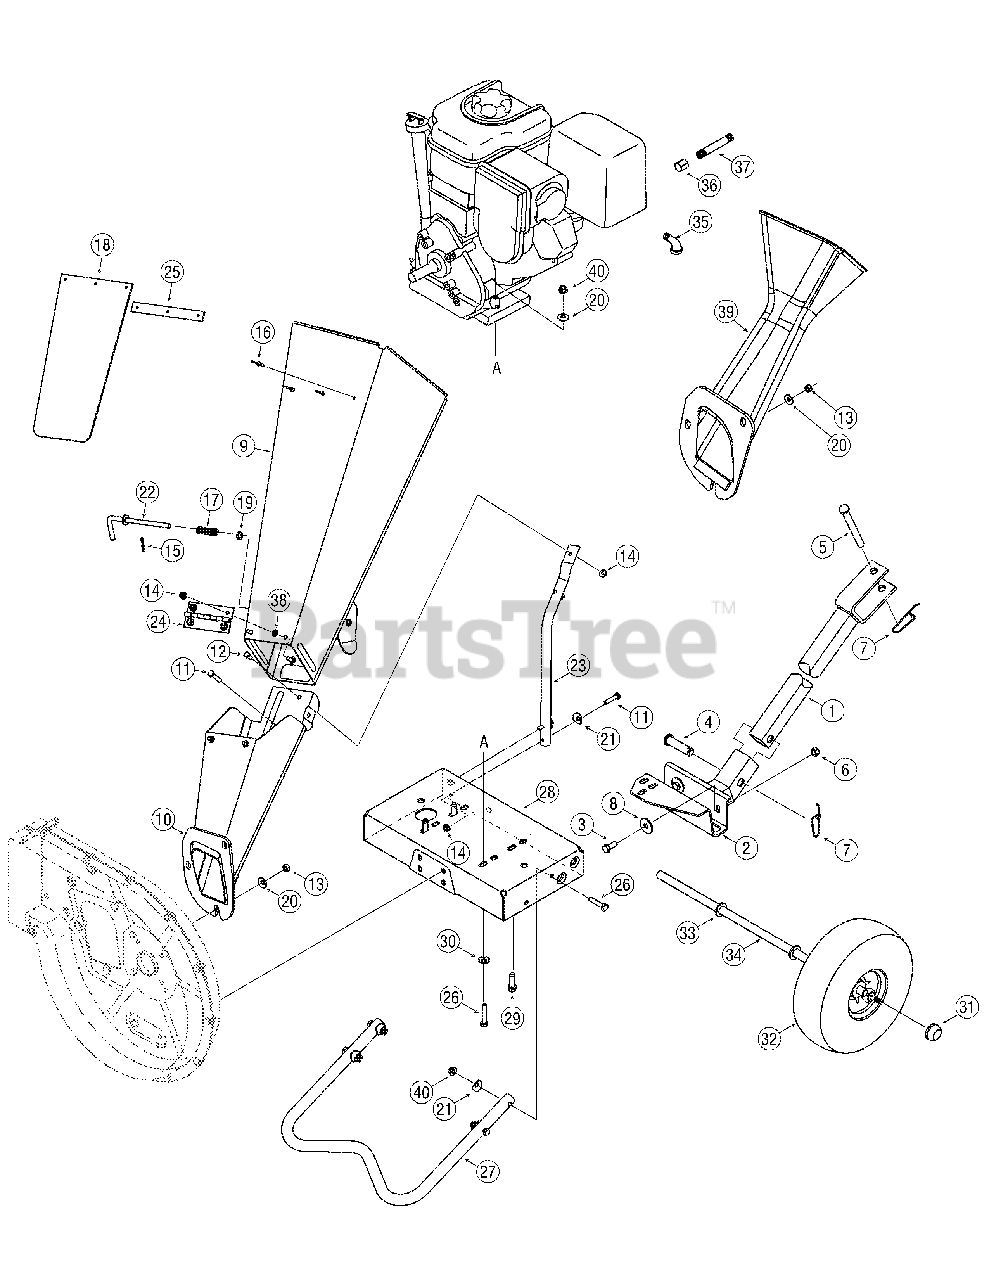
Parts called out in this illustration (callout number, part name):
3	Hex Cap Screw, 3/8-16 x.88
4	Clevis Pin,.625 x 2.4
5	Clevis Pin,.50 x 4.62
6	Flange Lock Nut, 3/8-16
7	Spring Pin
8	Flat Washer,.411 x 1.25 x 1.0
11	Hex Cap Screw, 1/4-20 x 1.25
12	Screw, 1/4-20 x .50
13	Hex Nut, 5/16-18
14	Flange Lock Nut 1/4-20
15	Cotter Pin
16	Pop Rivet
17	Compression Spring,.531 x 1.75
18	Chute Flap
19	Flat Washer
20	Bell Washer.340 ID x.872 OD
21	Washer,.320 ID x.93 OD
22	Lock Rod
24	Chipper Chute Hinge
25	Chute Flap Strip
26	Hex Cap Screw, 5/16-18 x 1.50
29	Hex Sems Screw, 3/8-16 x 1.25
30	Special Lock Washer, 5/16
31	Push Cap, 5/8
32	Wheel, 10 x 4 x 4
33	Flat Washer,.625 x 1.0
34	Axle, 22.47"
35	Elbow Fitting
36	Oil Drain End Cap
37	Oil Drain Pipe
38	Push Nut,.25ID x.50OD
40	Flange Lock Nut, 5/16-18
